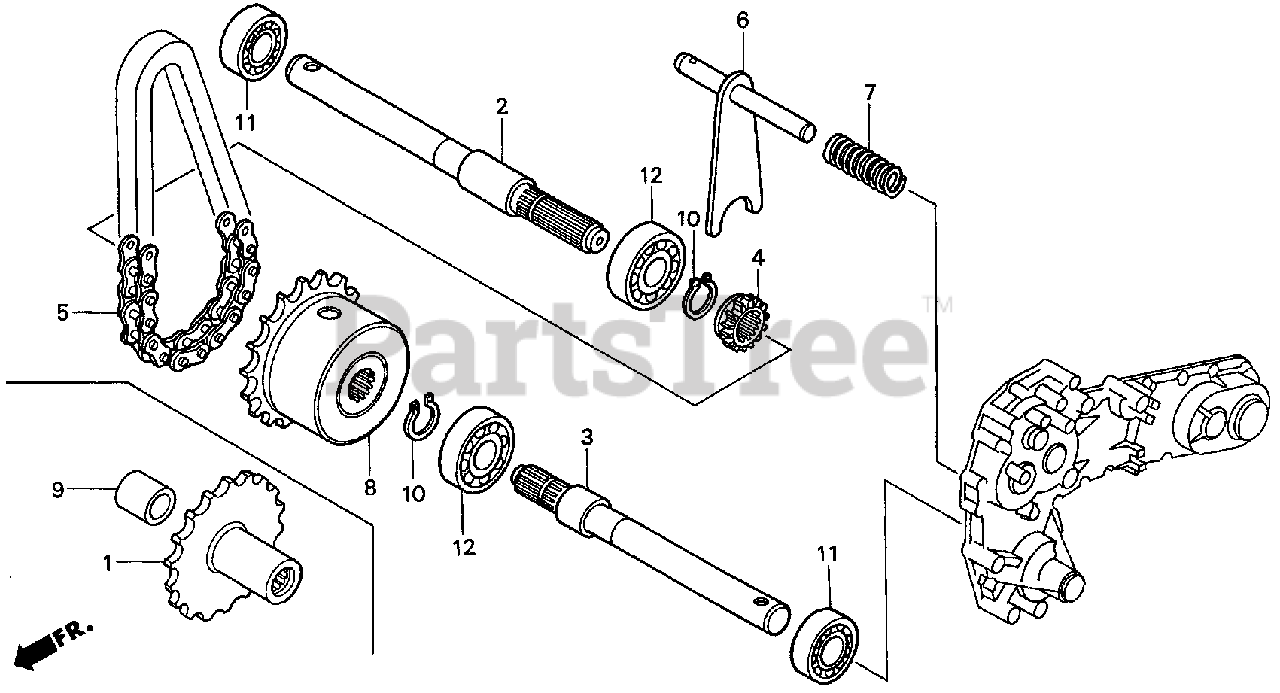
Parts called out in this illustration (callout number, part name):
1	SPROCKET, DRIVEN
2	SHAFT, R. WHEEL
3	SHAFT, L. WHEEL
5	CHAIN, FINAL
9	COLLAR, WHEEL SHAFT
10	CIRCLIP, OUTER (20MM)
11	BEARING, RADIAL BALL (6004)
12	BEARING, RADIAL BALL (6304)
